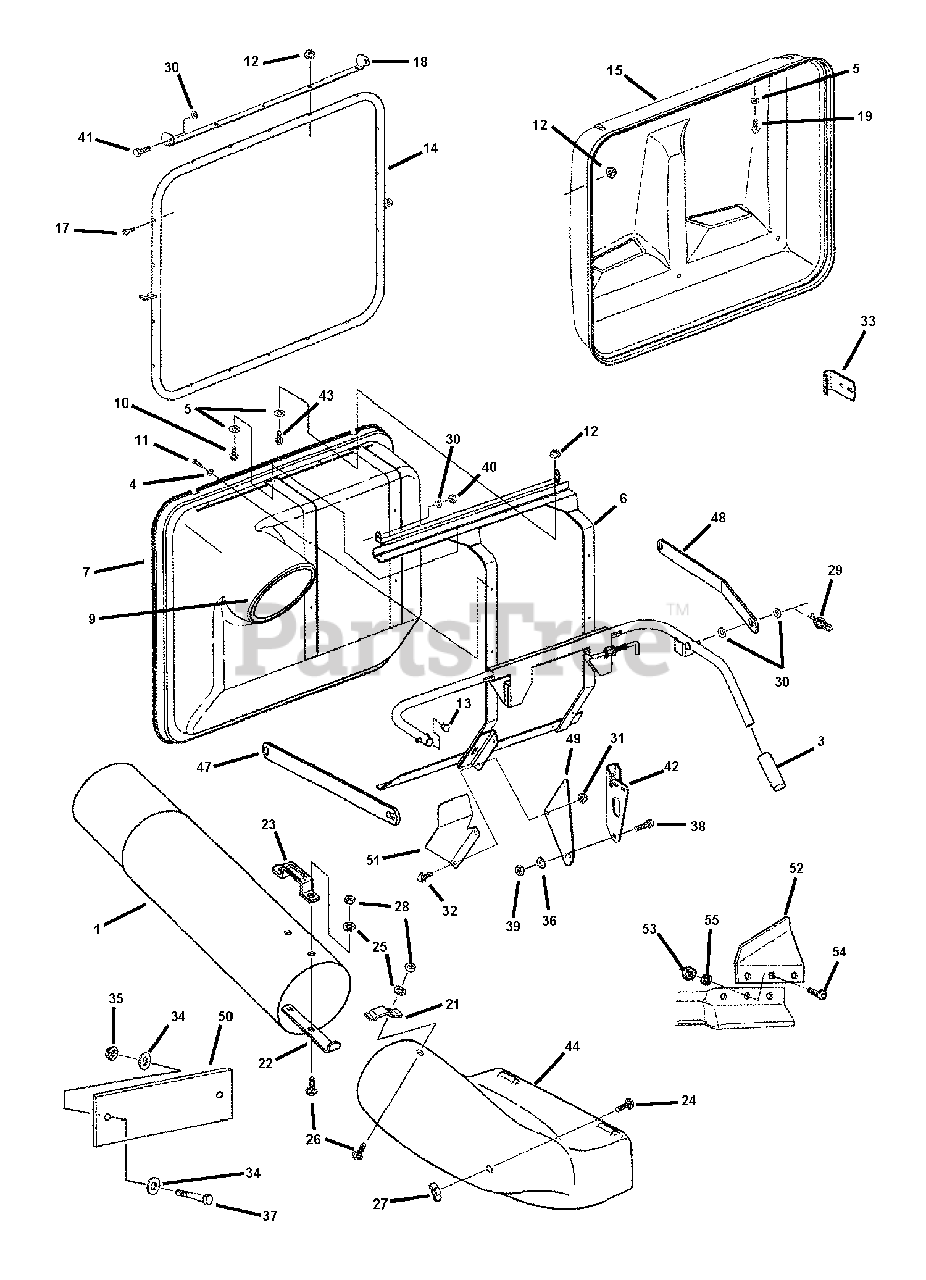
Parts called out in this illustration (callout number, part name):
1	TUBE, Grass (36 long)
3	GRIP
4	WASHER, 11/32 Flat
5	WASHER, 3/16 Flat, YZ
6	WELDMENT, Front Cover Brace
7	COVER, Front
9	GASKET, Chute
10	SCREW, #10-24 x 1/2 Self-Tap
11	SCREW, 1/4-20 x 5/8 Pan Head Self-Tapping
12	NUT, #10-24 Hex Flange Lock
13	END CAP, Tube
14	WELDMENT, Rear Cover Brace
15	COVER, Rear
17	BOLT, #10-24 x 1-1/2 Oval Hd.
18	HINGE, Rear Cover
19	SCREW, #10-24 x 1-1/2 Machine
21	* LATCH, Chute/Tube
22	* BASE, Handle
23	* HANDLE, Tube
24	* BOLT, 5/16-18 x 1 Carriage GR 5 YZ
25	* WASHER, 1/4 Int. Tooth Lock YZ
26	* BOLT, 1/4-20 x 3/4 Carriage YZ
27	* NUT, 5/16-18 Wing Lock YZ
28	* NUT, 1/4-20 Hex YZ
29	* PIN, 3/8 Self Lock Cotter YZ
30	* WASHER, 3/8" Flat
31	* NUT, 5/16-18 Flange Lock YZ
32	* BOLT, 5/16-18 x 5/8 Hex Flange Lock YZ
33	* SUPPORT, Bumper
34	* WASHER, 3/8" Flat
35	* NUT, 3/8-16 Hex Top Lock YZ
36	* WASHER, 1/2 Internal Tooth Lock
37	* BOLT, 3/8-16 x 3 Hex Cap Gr. 5
38	* BOLT, 1/2-13 x 1 Hex Cap Gr. 5
39	* NUT, 1/2-13 Hex Gr. B, YZ
40	* NUT, 3/8-16 Hex NYLock YZ
41	* SCREW, 3/8-16 x 1 Hex Cap YZ
42	* BRACE, Bumper
43	* BOLT, #10-24 x 3/4 Flange Lock
44	ASSEMBLY, Chute 28" & 33" (Includes items 45 & 46)
47	LINK, Handle (Right Hand)
48	LINK, Handle (Left Hand)
49	PLATE, Hitch
50	PLATE, Weight (5.6 #'s Each)
51	SHIELD, Heat (Honda)
52	Air Lift
53	NUT, 5/16-24 Hex
54	SCREW, 5/16-24 x 5/8 Oval Head Machine
55	WASHER, 5/16 Int. Tooth Lock
